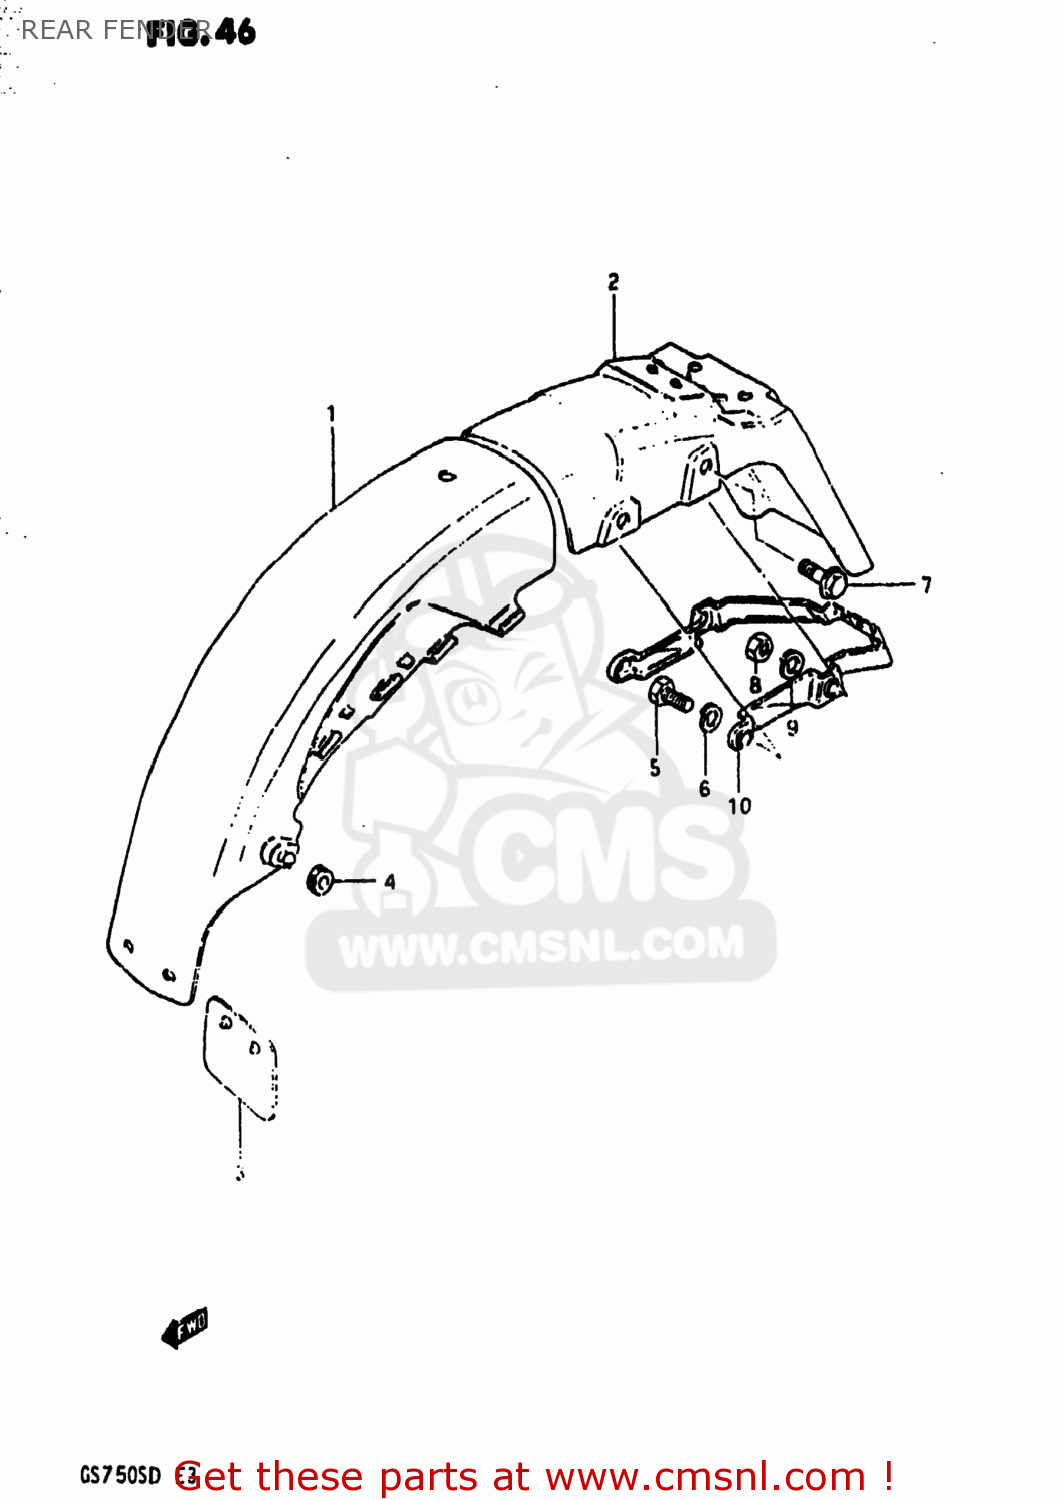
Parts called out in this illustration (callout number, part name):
1	FENDER,REAR
2	BODY,RR FENDER RR
3	GUIDE,RR FENDER MUD
4	CUSHION
5	BOLT, UPPER
6	LOCK WASHER
7	BOLT
8	NUT
9	LOCK WASHER
10	REINFORCEMENT,RR FENDER
